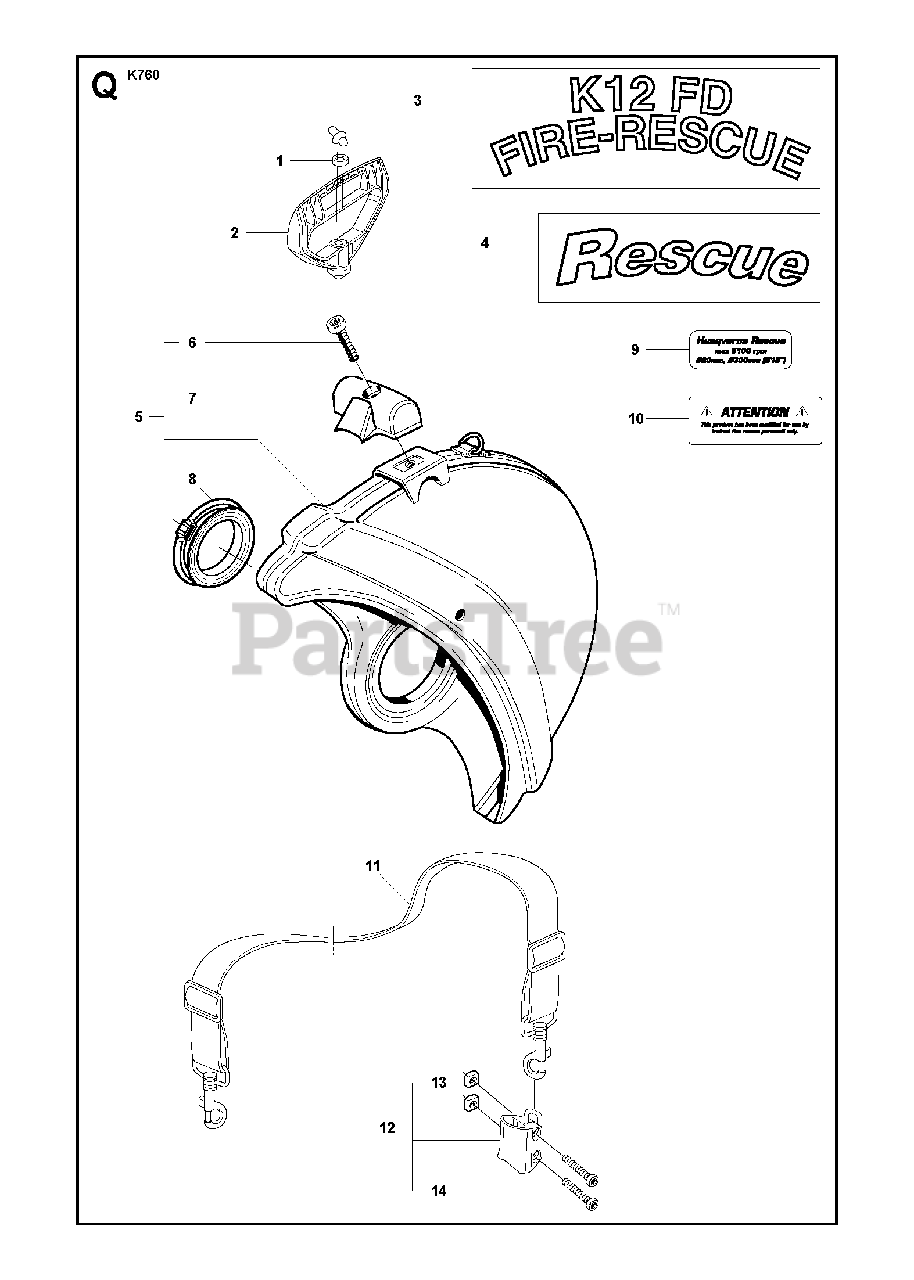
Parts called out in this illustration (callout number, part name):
2	STARTER HANDLE
5	BLADE GUARD
6	SCREW ITXSCM
14	SCREW ITXSCM
